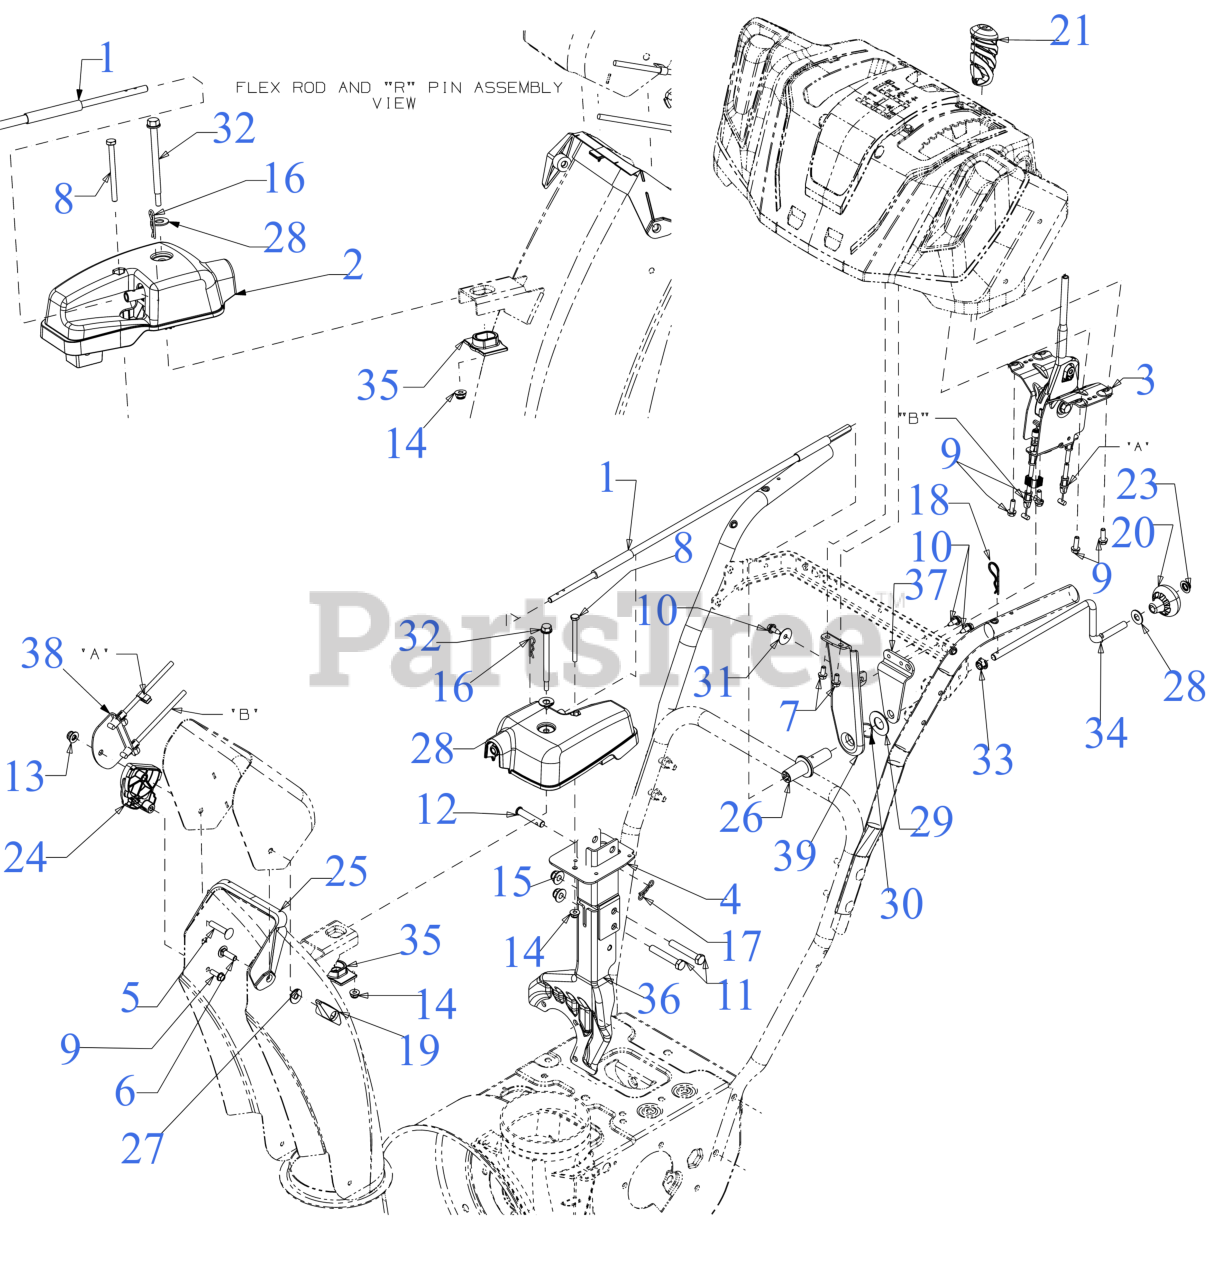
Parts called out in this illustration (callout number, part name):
1	CHUTE CONTROL
2	2-WAY CHUTE ROTATE GEARBOX
3	2-WAY STEEL CHUTE CONTROL ASSEMBLY
4	EXTENSION CHUTE MAST
5	CARRIAGE BOLT 5/16-18 x 1.50
6	CARRIAGE BOLT 5/16-18 x 1.00
7	HEX SCREW 1/4-15 x .50
8	SCREW 1/4-20 x 3.0 GR5
9	SCREW 1/4-15 x .750
10	SCREW 1/4-20X.625
11	SCREW 3/8-16 x 2.25 GR5
12	CLEVIS PIN 3/8 x 1.87
13	FLANGE LOCK NUT 5/16-18
14	FLANGE LOCK NUT
16	INTERNAL COTTER PIN
17	BOW TIE COTTER PIN 1/4-5/16
18	INTERNAL COTTER PIN
19	WING KNOB NUT
20	SHIFT KNOB
21	PTO HANDLE GRIP .355 ID
24	CHUTE TILT GUIDE
25	UPPER CHUTE ADAPTER
26	CHUTE ROD COUPLER
27	FLAT WASHER
28	FLAT WASHER
29	FLAT WASHER
30	WAVE WASHER .785X1.00X.012
31	FLAT WASHER
32	SHOULDER SCREW
33	BUSHING .380 ID
34	CHUTE CRANK (POWDER BLACK)
35	HELICAL GEAR CHUTE ADAPTER
37	ROD SUPPORT BRACKET
